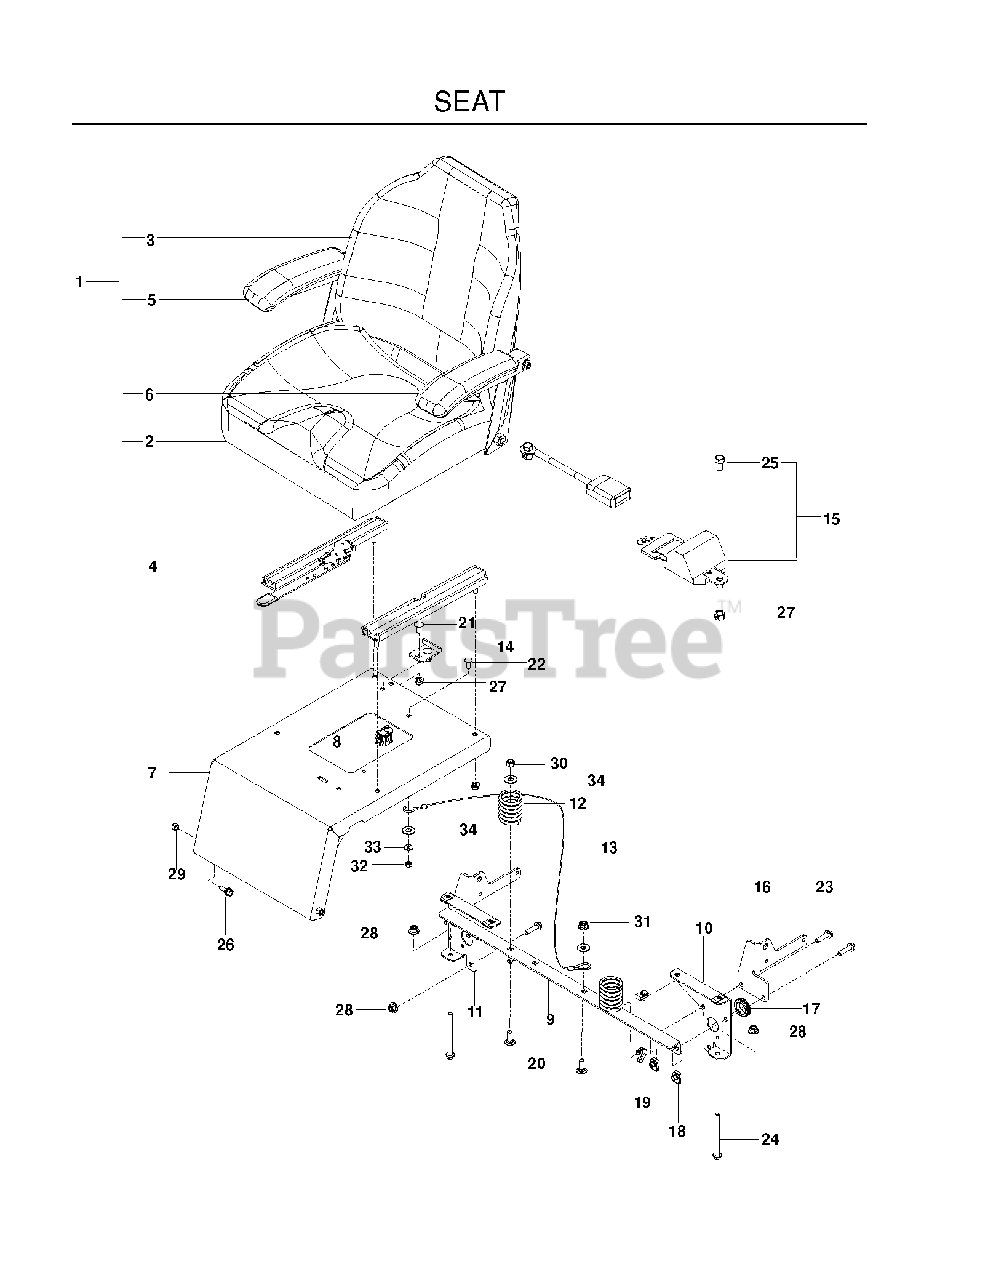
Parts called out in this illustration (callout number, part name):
8	SEAT SWITCH
9	SUPPORT, SEAT
10	SUPPORT, LT, BLK
11	SUPPORT, RT, BLK
12	SPRING, SEAT
13	SEAT LANYARD
14	STOP, SEAT - BLACK
16	MOUNT, SEAT BELT, BLACK
17	RUBBER GROMMET
18	U-CLIP 5/16-18 NUT RETAINER
19	TIE WRAP, 8-3/8", W/CLIP
20	RHSNB 3/8C X 1
21	RHSNB 5/16-18 X 3/4
22	RHSNB 1/4C X 3/4
23	HHFS 5/16-18 X 1.25 TPBLT GD 5
24	HHFS 5/16-18 X 3 3/4
25	HCS 7/16-20 X .75 GD 5
26	SB 5/16-18 HEX HD GD5, BLK ZN
27	NUT HEX 7/16F LOCK RP
28	5/16-18 NYLOC FLANGE NUT
29	NUT 5/16 NYLOC
30	NUT 3/8-16 NYLOC
31	NUT 3/8-16 HEX FLG NYLOC ZD
32	NUT 1/4-20 NYLOC
33	WASHER 1/4 FLAT
34	WASHER 3/8 FLAT
